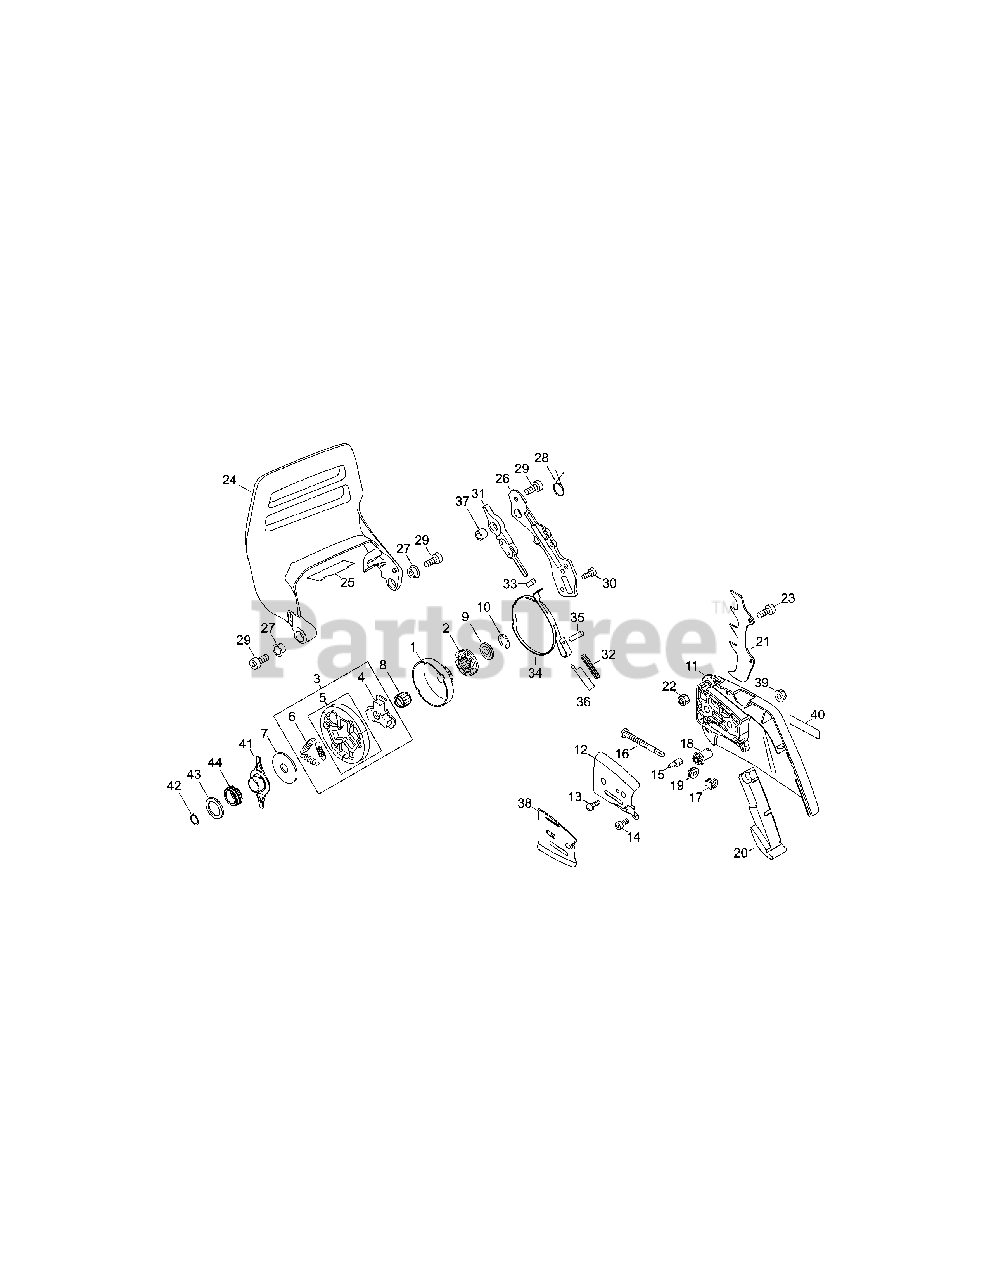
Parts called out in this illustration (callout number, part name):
1	DRUM, CLUTCH
2	SPROCKET, RIM 3/8"×7T
3	CLUTCH ASSY
4	HUB, CLUTCH
5	SHOE SET, CLUTCH (3PCS)
6	SPRING, TENSION
7	PLATE, CLUTCH
8	BEARING, NEEDLE 10
9	WASHER 10
10	E-RING Ø8.1
11	GUARD, SPROCKET
12	PLATE, GUIDE - OUTER
13	SCREW 3×5
14	BOLT, TORX 4×12
15	TENSIONER, CHAIN
16	SCREW, CHAIN TENSION 63 MM
17	COLLAR 8
18	GEAR, BEVEL
19	GEAR, BEVEL
20	CUSHION
21	SPIKE, BUMPER
22	NUT, LOCK M5
23	BOLT, TORX 5×12
24	LEVER, BRAKE
25	SHIELD, HEAT 75×27×0.15
26	COVER, BRAKE
27	COLLAR 11.2×16.2×T0.6
28	SPRING, TORSION
29	BOLT, TORX 5×16
30	BOLT, TORX 4×12
31	CONNECTOR, BRAKE
32	SPRING, COMPRESSION Ø12×70.5
34	BAND, BRAKE
35	PIN, SPRING 3x-9.8
36	PLATE, SIDE
37	SPACER 12×10×T: 1.0
38	PLATE, GUIDE - INNER
40	LABEL, ECHO
41	COLLAR 15×19×73
42	RING, RETAINING 15
43	WASHER 15.5×22.5×0.5
44	GEAR, WORM
